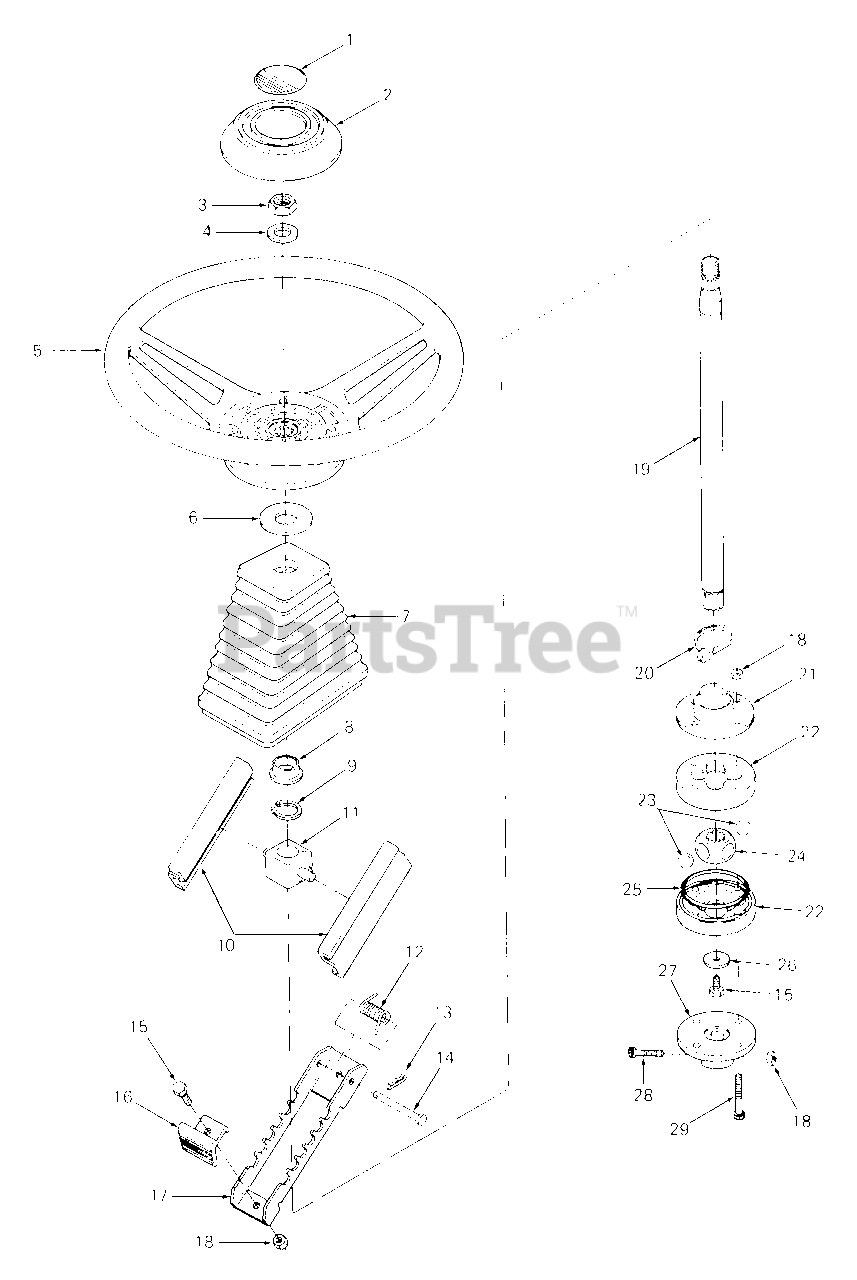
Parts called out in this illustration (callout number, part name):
1	Label, Steering Cap
2	Cap, Steering Wheel
3	Nut, Hex Jam, 5/8-18
4	Washer, Flat, .640 X 1.24 X .06 Thk HDN
5	Wheel, Steering
6	Washer, Flat, .758 X 2.0 X .030 Thk
7	Boot, Steering Shaft
8	Bearing, Flange
9	Ring, Snap
11	Bushing, Shaft Guide
12	Spring-Tilt, Torsion
13	Pin, Internal Cotter
14	Pin, Clevis, .25 Dia X 2.38 Lg
15	Screw, Hex Cap, 1/4-20 X .50 Lg GR5
16	Button, Tilt Control
17	Plate, Tilt Control
18	Nut, Hex Patch Lock, 1/4-20
19	Shaft, Upper Steering, 16.75 Lg
20	Strap, Tie
21	Boot, Coupling
22	Coupling, Drive w/O-Ring Groove
23	Ball, Steel, 5/8 Dia Chrome
24	Hub, Drive
25	O-Ring, 2.489 X .070
26	Washer, Flat, .265 X 1.0 X .030 Thk HDN
27	Adapter, Steering
28	Screw, Socket Hd Cap, 1/4-20 X 1.12 Lg
29	Screw, Socket Hd Cap, 1/4-20 X 1.75 Lg
